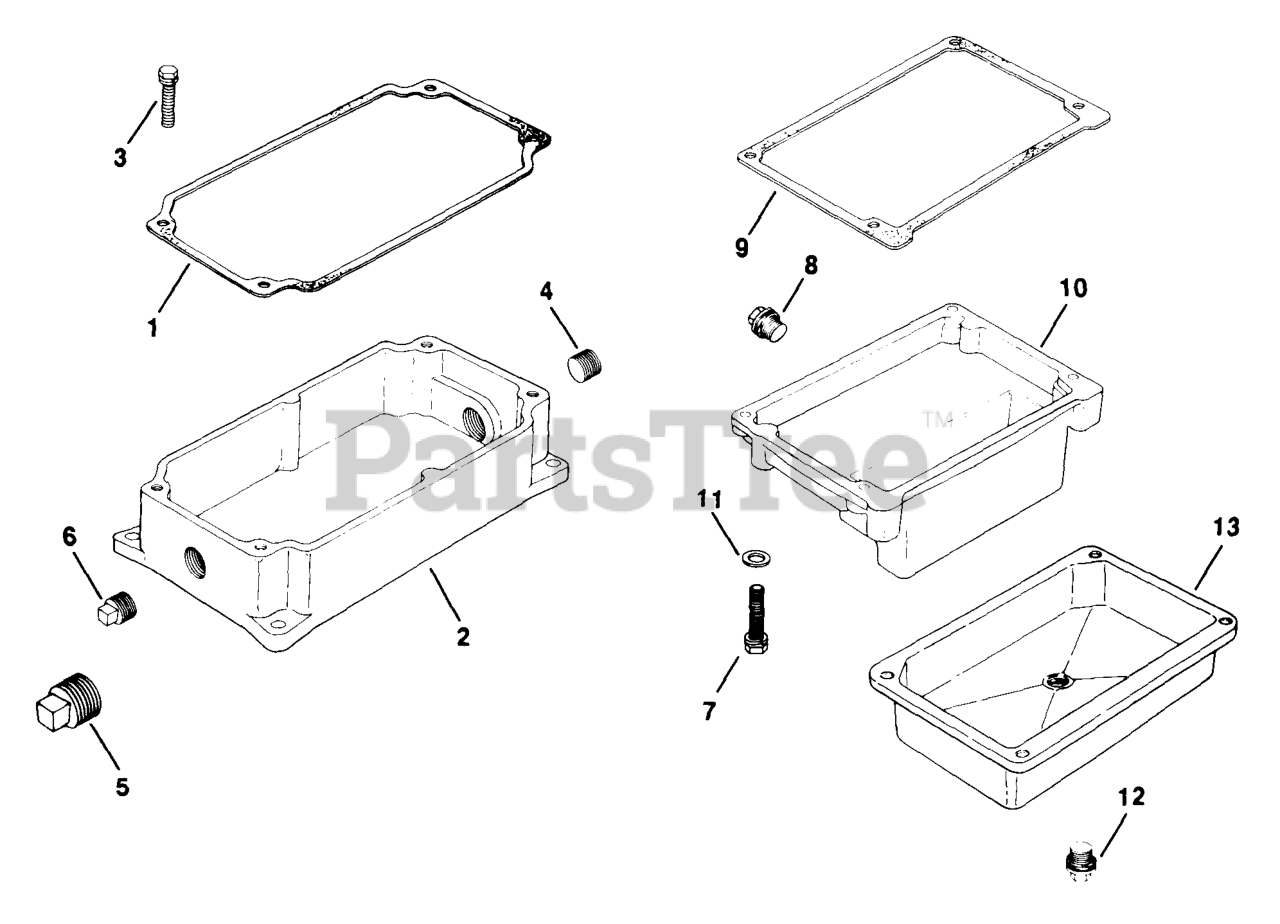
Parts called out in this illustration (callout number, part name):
1	GASKET, OIL PAN
2	PAN - DISCONTINUED
3	SCREW, SEMS 3/8-16X1-1/4" - DISCONTINUED
4	PLUG,PIPE 1/2 NPTF SQUARE HD USE 25 139 54-S
5	PLUG,PIPE SQ HD 3/4" USE 25 139 56-S
